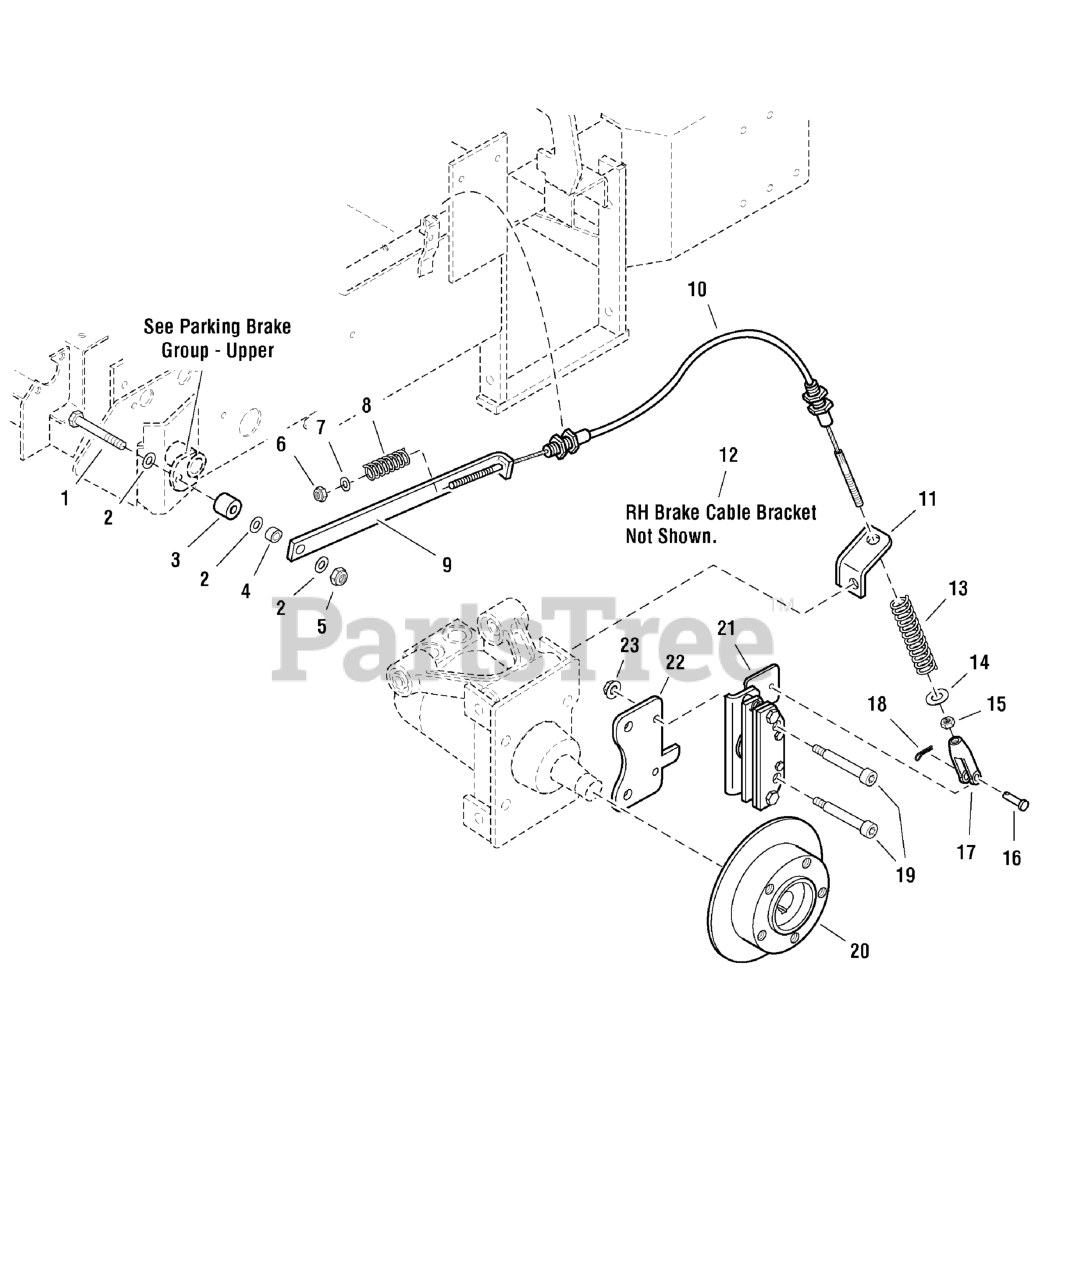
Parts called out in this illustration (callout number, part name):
1	BOLT, 3/8-16 X 2-1/4" GD5 CZ
2	WASHER, 3/8 SAE
3	SPACER, .39 x 1.00 x .88
4	SPACER, .38 x .50 x .27
5	NUT, 3/8-16 HEX NYLON LOCK
6	NUT, 5/16-24 HEX NYLON LOCK
7	WASHER, 5/16" SAE
8	SPRING, Compression
9	LINK, Brake Lock
10	CABLE, Brake
11	BRACKET, Cable Mount-LH
13	SPRING, Compression
14	WASHER, 5/16" Fender
15	NUT, 5/16-24 Hex
16	CLEVIS PIN, 5/16 x 1
17	CLEVIS, 5/16-24, STEEL, CLEAR ZINC
18	PIN, COTTER, 1/8 X 1-1/4
19	SHOULDER BOLT, 1/2" x 2-3/4"
20	WHEEL HUB, COMPACT CALIPER (86720)
21	BRAKE CALIPER
22	BRAKE CALIPER MOUNT
23	NUT, 3/8-16 Hex Serrated Flange
